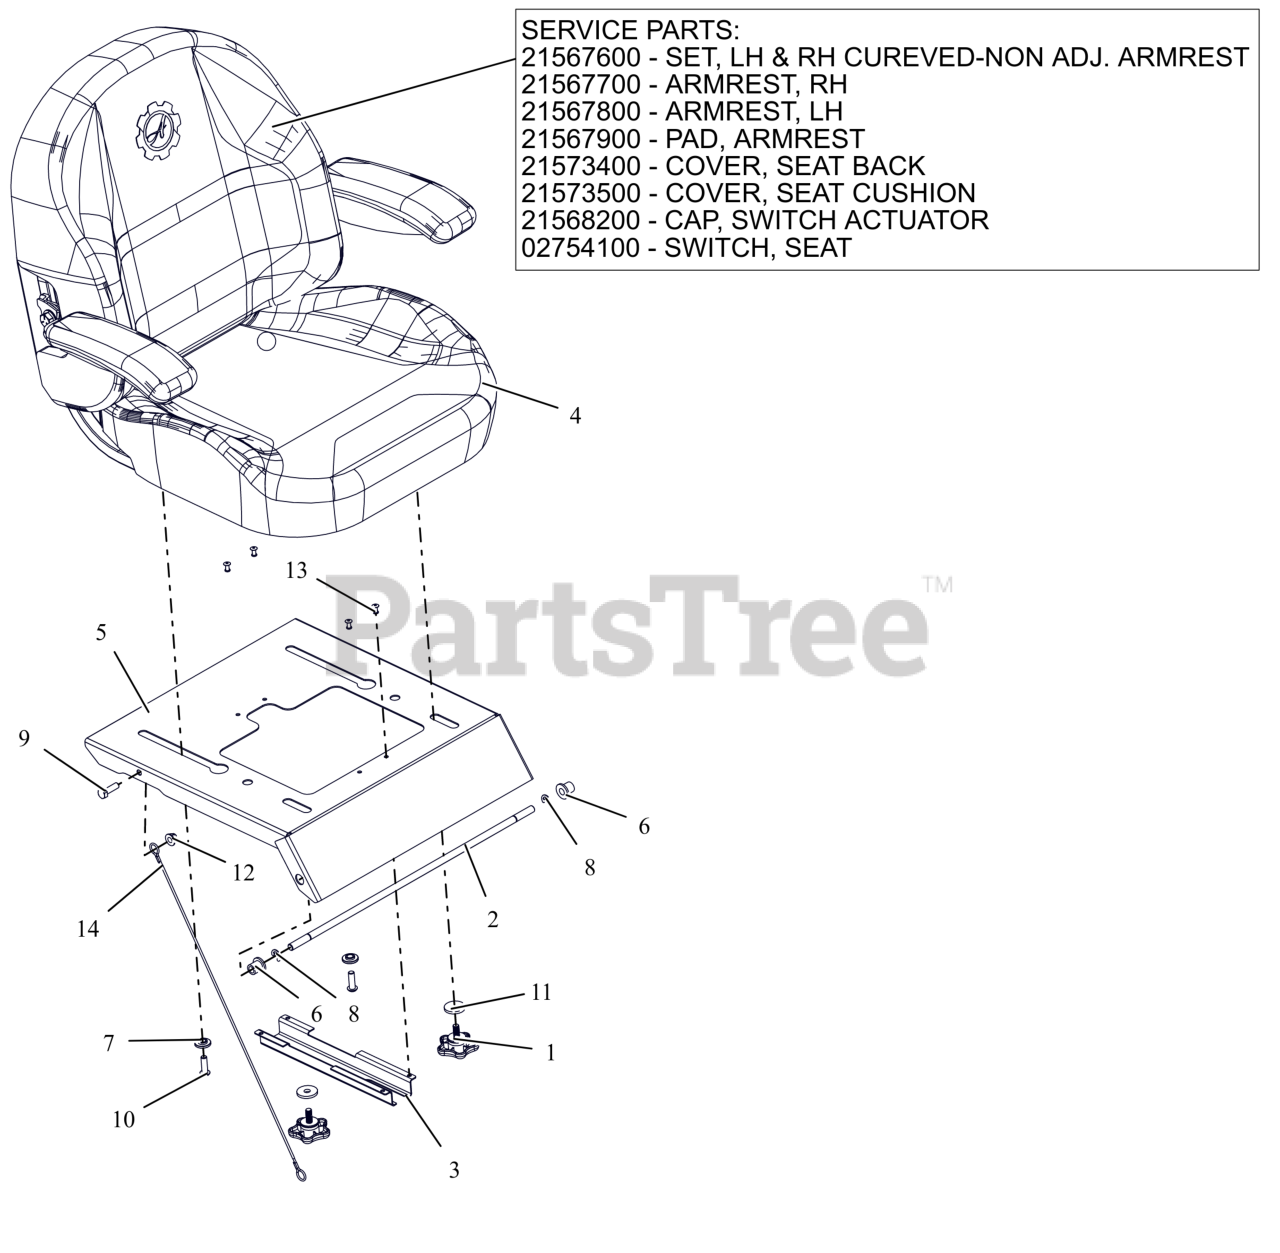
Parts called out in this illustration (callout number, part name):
1	KNOB, WING STUDDED
2	ROD, SEAT PIVOT
3	GUARD, SEAT SWITCH (GREY PEARL)
4	SEAT, 2020 IKON
4	SET,LH&RG CURVED-ARMREST
4	ARMREST-CURVED RH
4	ARMREST-CURVED LH
4	PAD, ARMREST (BLACK SELFSKIN)
4	COVER, SEAT BACK
4	COVER, SEAT CUSHION
4	CAP, SWITCH ACTUATOR
4	SWITCH- SNAP MTG N.O.
5	PLATE, SEAT (FASTENER SLIDE) (ORANGE)
6	BSHG-FLG .38X.580X.667X.750
7	BSHG, FLG .312X.499X.23X.88
8	RG-RTNG-EXT .375X.035 TYP E
9	BLT,HEX .31-18X1.00 G5 ZCC
10	BLT,SHCS-BTN .31-18X1.00 ZCC
11	WSHR, FLT .340X1.125X.135 ZCC
12	NUT,LK-NYL-FLG .31-18 G5ZC120
13	RVT-POP.187X.527 DOME ST
14	LANYARD, SEAT CABLE .093X19.5
